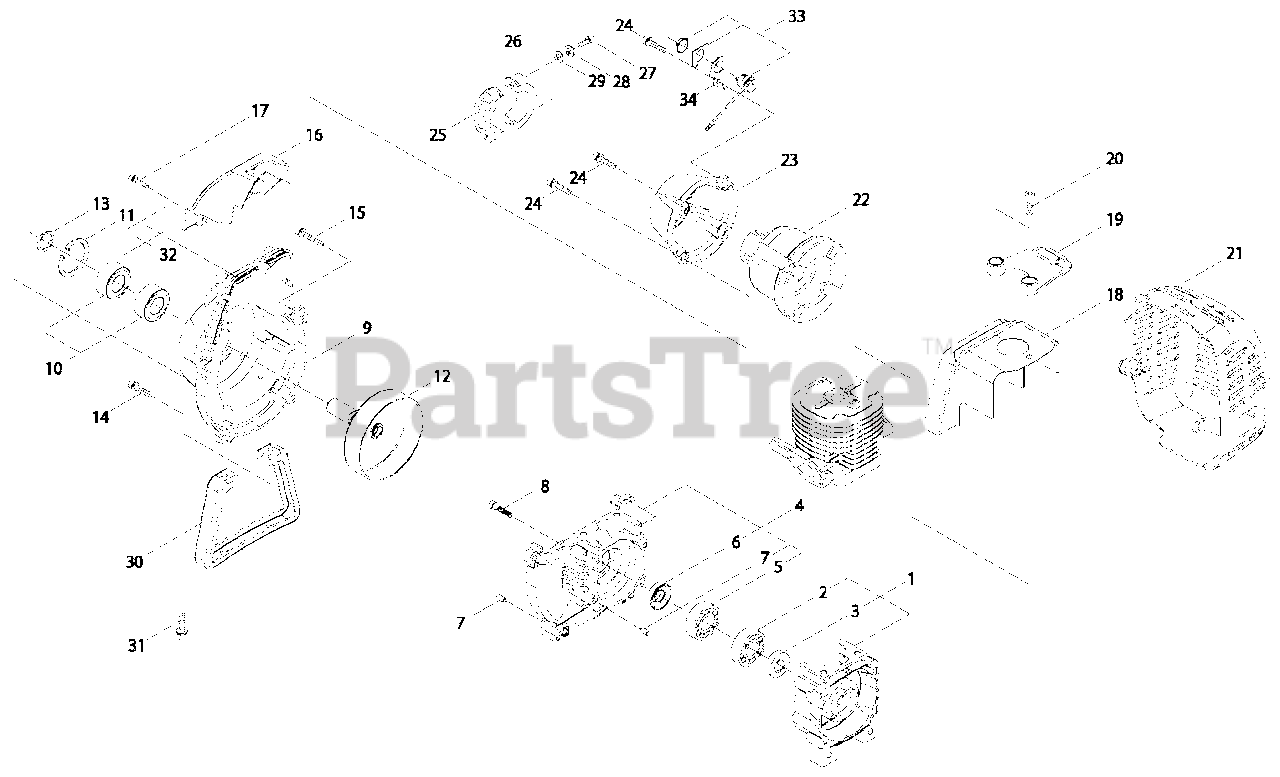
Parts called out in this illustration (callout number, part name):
1	CRANKCASE ASSY - REAR
2	BEARING, BALL - 6202C3
3	SEAL, OIL - 15
4	CRANKCASE KIT - FRONT
5	BEARING, BALL - 6202C3
6	SEAL, OIL - 15
7	PIN - LOCATING
8	SCREW - 5X30
9	CASE, FAN
10	BEARING, BALL - 6002
11	RING, RETAINING - 32
12	DRUM, CLUTCH
13	RING, RETAINING
14	SCREW - 5X20
15	SCREW - 5X30
16	PROTECTOR
17	SCREW - 4X16
18	COVER, ENGINE
19	BRACKET
20	SCREW - 5X18
21	COVER, EXHAUST
22	CUSHION
23	CONNECTOR, CAP
24	SCREW - 5X20
25	CLAMP - A
26	CLAMP - B
27	SCREW - 5X25
28	LOCKWASHER - 5
29	WASHER - 5
30	GUARD, FUEL TANK
31	SCREW - 5X16
32	LABEL - MODEL
33	SWITCH, IGNITION
34	BRACKET, SWITCH
